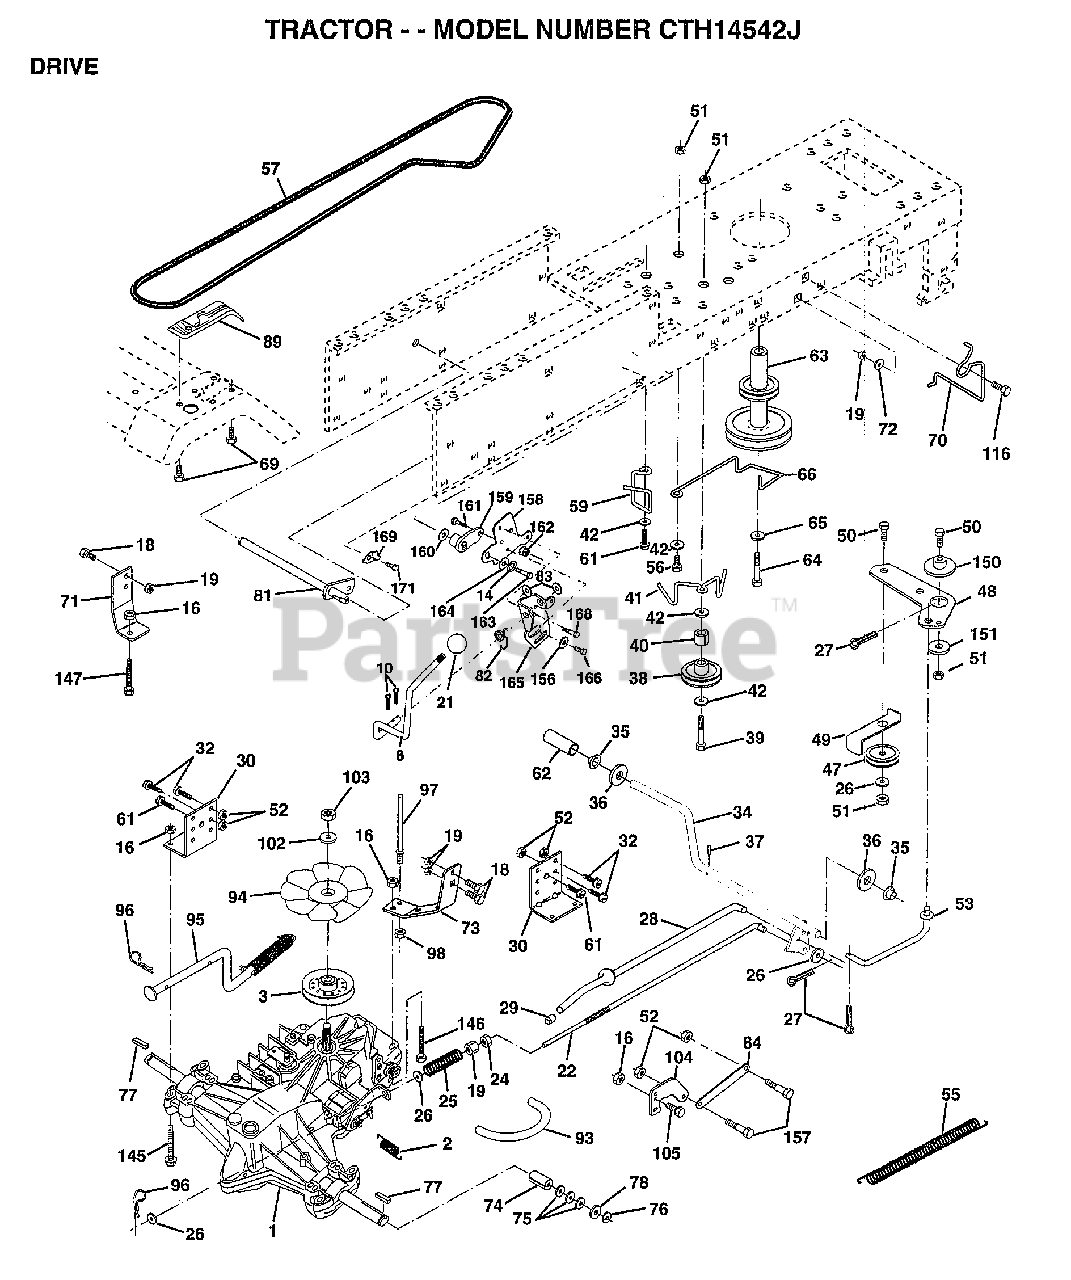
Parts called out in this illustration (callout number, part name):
1	TRANSAXLE.3100650
2	SPRING RET BRAKE
3	PULLEY.TRANSAXLE
8	ROD.SHIFT.FENDER.ADJ.LT.CRD
10	PIN COTTER 1/8
14	LOCKWASHER
16	NUT
18	BOLT
19	NUT
21	KNOB DLX BLK/BLK
22	ROD.BRAKE.HYDRO.
24	NUT
25	SPRING ROD LT
26	WASHER
27	COTTER PIN
28	ROD.BRAKE.PARK.LT
29	PLUNGER CAP T
30	TRANSAXLE MTG BKT
32	BOLT
34	SHAFT ASM-PEDAL F
35	NYLON BEARING
36	WASHER LT
38	FLAT IDLER PULLEY
39	BOLT
40	SPACER T
41	"KEEPER,BELT.IDLER FLAT"
42	WASHER
48	BELLCRANK.CLUTCH
49	RETAIN BELT
53	"LINK, CLUTCH T"
55	"SPRING, RETURN LT"
57	"BELT.GD DRV 82"""
59	KEEPER BELT CNTSP
61	SCREW
62	PEDAL COVER T
63	PULLEY.ENGINE
64	BOLT
65	LOCKWASHER
66	KEEPER-BELT
69	SCREW HEXWSH H-L
70	KEEPER BELT ENG
71	STRAP TORQ LH HYD
72	WASHER
73	"STRAP-TORQUE,RH"
74	SPACER SPLIT
75	WASHER
76	E-RING LT
77	SQUARE KEY
78	WASHER
81	SHAFT.ASM.CROSS
82	"SPRING,TORSION"
83	WASHER
84	LINK.TRANSAXLE.LT/YT
89	CONSOLE.SHIFT.LT
93	"LINE FUEL HYD 4"""
94	"FAN 7"" HYDRO"
95	CONTROL.ASM.BYPASS.HYDRO.99
96	RETAINER M
97	BOLT KEEPER RH
98	NUT
102	WASHER BELLEVILLE
104	ARM CONTROL HYDRO
105	SCREW CAP 5/16-18
116	BOLT RDHD 3/8-16
145	BOLT.HEX.FLGHD
146	BOLT.HEX.FLGHD.
147	BOLT.HEX.FLGHD
150	BUSHING.BELLCRANK.GRD.DR
151	WASHER
156	WASHER.SRRTD.5/16
157	"BOLT,SHOULDER"
158	BRKT.SHIFT.MOUNT
159	HUB.SHIFT
160	WASHER
161	BOLT T
164	WASHER.5/8X.281X10GA
165	BRKT.PIVOT.LEVER
166	SCREW.5/16-18X5/8
168	BOLT.SHOULDER.5/16-18X.561
169	PLATE.FASTENING
171	SCREW LT
